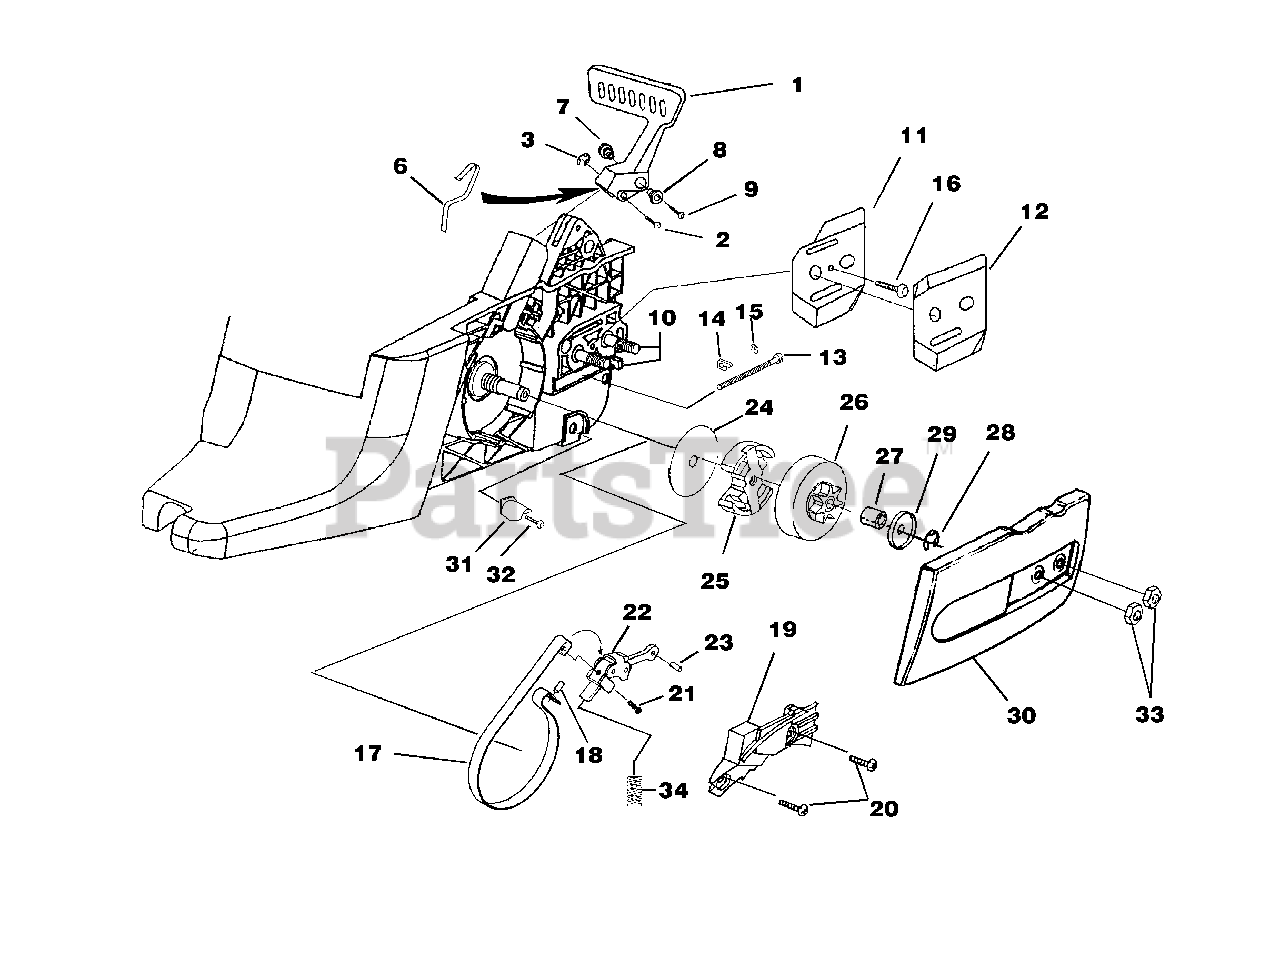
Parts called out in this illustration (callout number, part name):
1	Hand Guard Kit
2	Hand Guard Actuating Pin
3	Retaining Ring
6	Spring, Handguard
7	Pivot, L.H.
8	Pivot, R.H.
9	Screw, Hex Socket Hd. (8-32 x 5/8")
10	Guide Bar Bolt
11	Plate, Guide Bar
12	Plate, Guide Bar
13	Screw, Guide Bar Adjusting
14	Pin, Guide Bar Adjusting
15	Ring, Retaining
16	Screw, Thread Form (6-19 x 1/2")
17	Chain Brake Kit
18	Pin, Roll
19	Cover, Chain Brake
20	Screw, Pan Hd. (6-19 x 1/2")
21	Screw, Pan Hd. (8-16 x .320)
22	Chain Brake Link
23	Pin, Roll
24	Thrust Washer
25	Clutch & Hardware
26	Sprocket, Drum (3/8 Pitch)
27	Bearing, Needle
28	Ring, Retaining
29	Washer, Cupped
30	Drive Case Cover
31	Stop, Chain
32	Screw, Thread Form (10-14 x 3/4")
33	Nut, Hex
34	Spring, Compression
